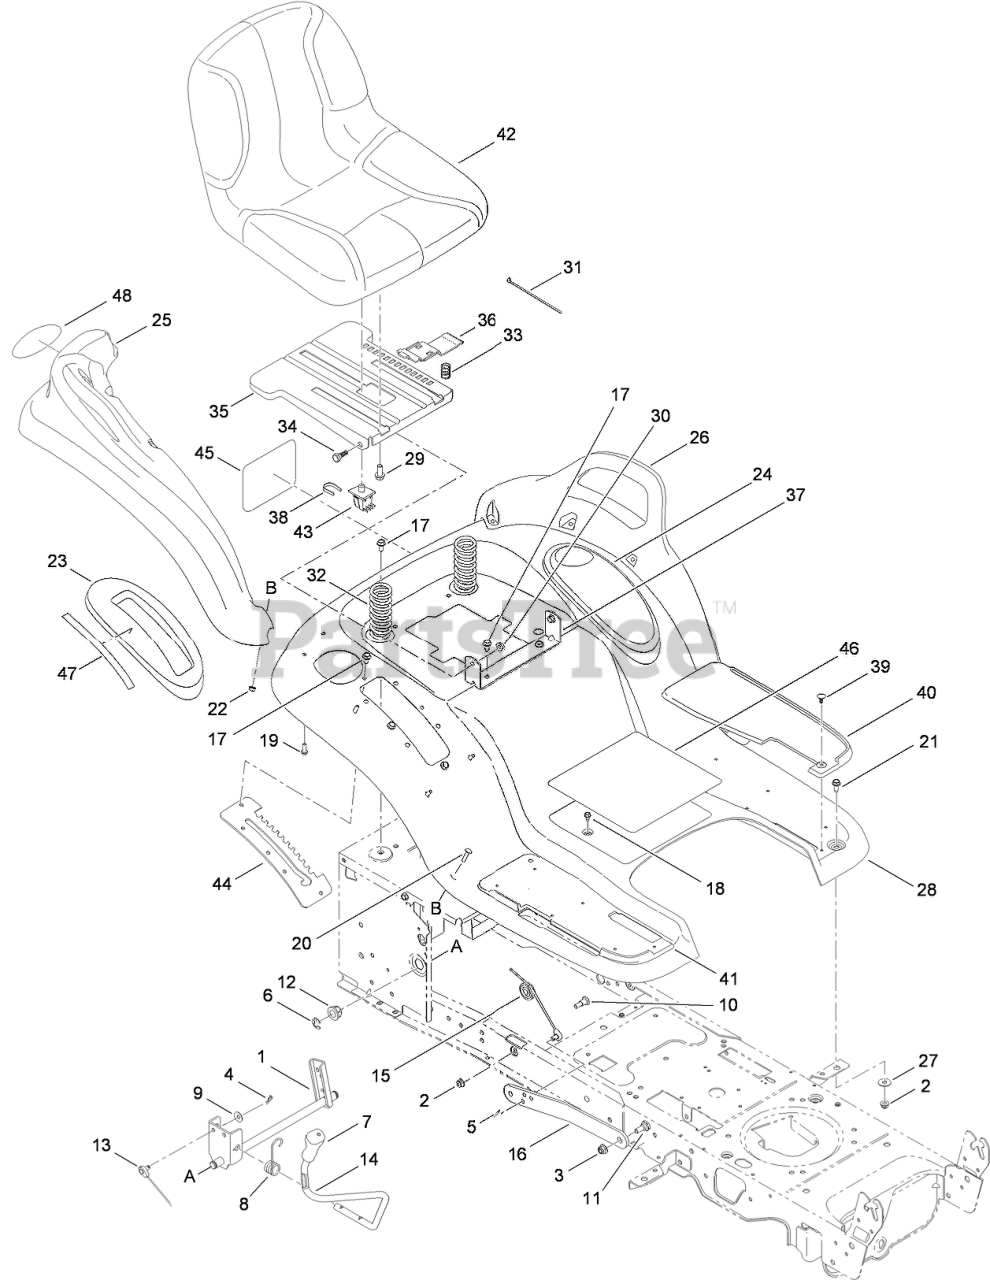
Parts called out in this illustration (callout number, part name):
1	LIFT SHAFT ASM
2	NUT-LOCK, FLANGE
3	NUT-LOCK, FLANGE
4	PIN-COTTER
5	PIN-COTTER
6	RING-E
7	GRIP-HANDLE
8	SPRING-TORSION
9	WASHER-SPRING
10	BOLT-SHOULDER
11	BOLT-SHOULDER
12	BEARING-FLANGE
13	CABLE-LIFT
14	HANDLE-LIFT
15	PULLEY-CABLE
16	ARM-LIFT
17	SCREW-TAP
18	SCREW-HWHTF
19	SCREW-TAP
20	SCREW-CARR
21	SCREW-HWH
22	NUT-SEMS
23	COVER-LIFT, LEVER
24	COVER (W/CUP HOLDER)
25	FLARE-FENDER, RH
26	FLARE-FENDER, LH
27	WASHER-FLAT
28	FENDER
29	SCREW-HH
30	NUT-LOCK, FLANGE
31	TIE-CABLE
32	SPRING-COMPRESSION
33	SPRING-COMPRESSION
34	BOLT-SHOULDER
35	BRACKET-MOUNT, SEAT
36	LEVER-ADJUSTMENT, SEAT
37	BRACKET-PIVOT, SEAT
38	CLIP-RETENSION
39	CLIP-RATCHET, FASTENER
40	PAD-FOOT, LH
41	PAD-FOOT, RH
42	SEAT-HIGH
43	SWITCH-SEAT
44	BRACKET-LIFT
45	DECAL-TORO
46	DECAL-SAFETY
47	DECAL-HOC
48	REFLECTOR
